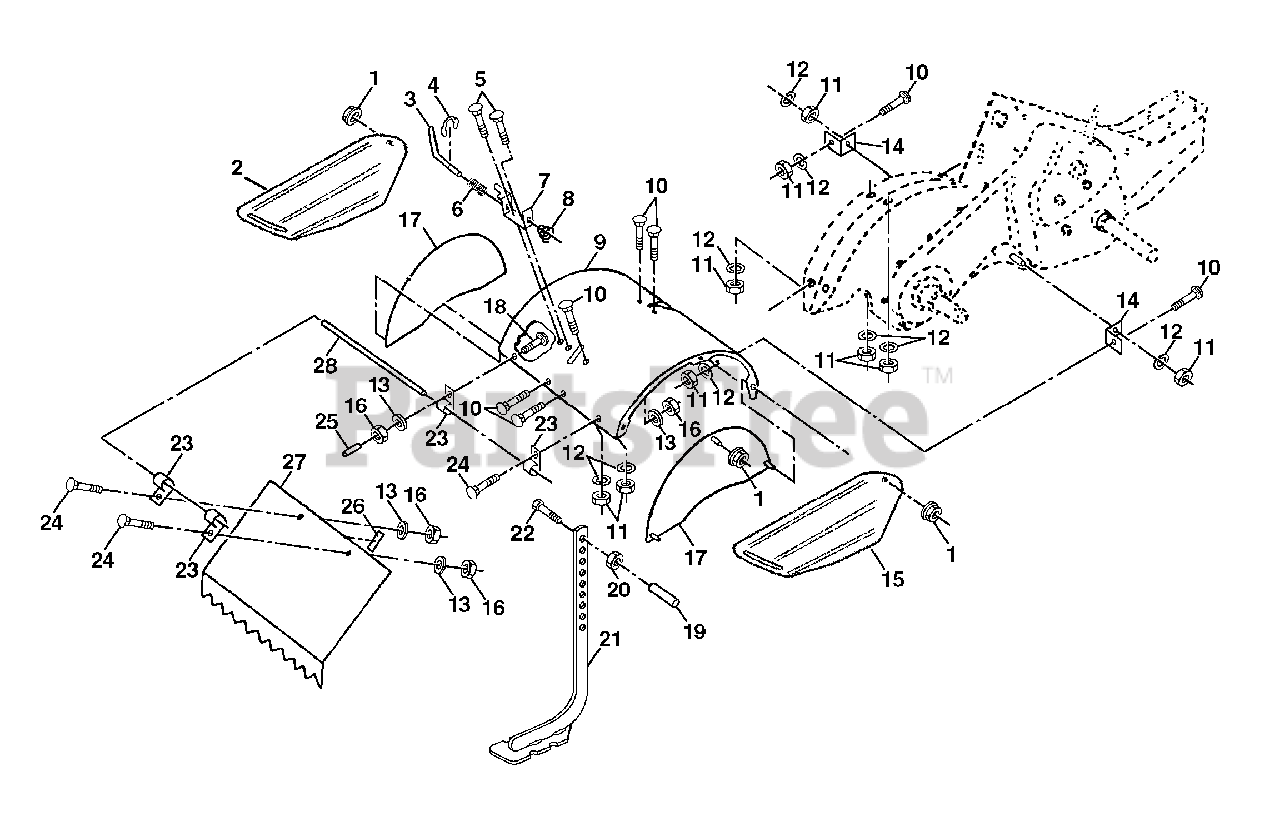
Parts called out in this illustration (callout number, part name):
1	Nut, Flange 5/16-18
2	Shield, Side, Outer L. H.
3	Pin, Stake, Depth
4	Ring, Klip
5	Bolt, Carriage 5/16-18 x 3/4 Gr. 5
7	Bracket, Latch
8	Spring, Depth Stake
9	Shield, Tine
10	Bolt, Carriage 5/16-18 x 1
11	Nut, Hex 5/16-18
12	Washer, Lock 5/16
13	Bolt, Carriage 5/16-18 x 1-1/4
14	Bracket, Shield Tine
15	Shield, Side, Outer R.H.
16	Nut, Keps Hex 1/4-20
18	Bolt, Carriage 1/4-20 x 1-1/4 Gr. 5
20	Nut, Hex 3/8-16
21	Stake, Depth
22	Bolt, Hex 3/8-16 x 2
24	Bolt, Carriage 1/4-20 x 1/2 Gr. 5
25	Cap, Vinyl
26	Pad, Idler
27	Shield, Leveling
28	Pin, Hinge
29	Shield, Side
30	Nut, Lock Hex, Flange
